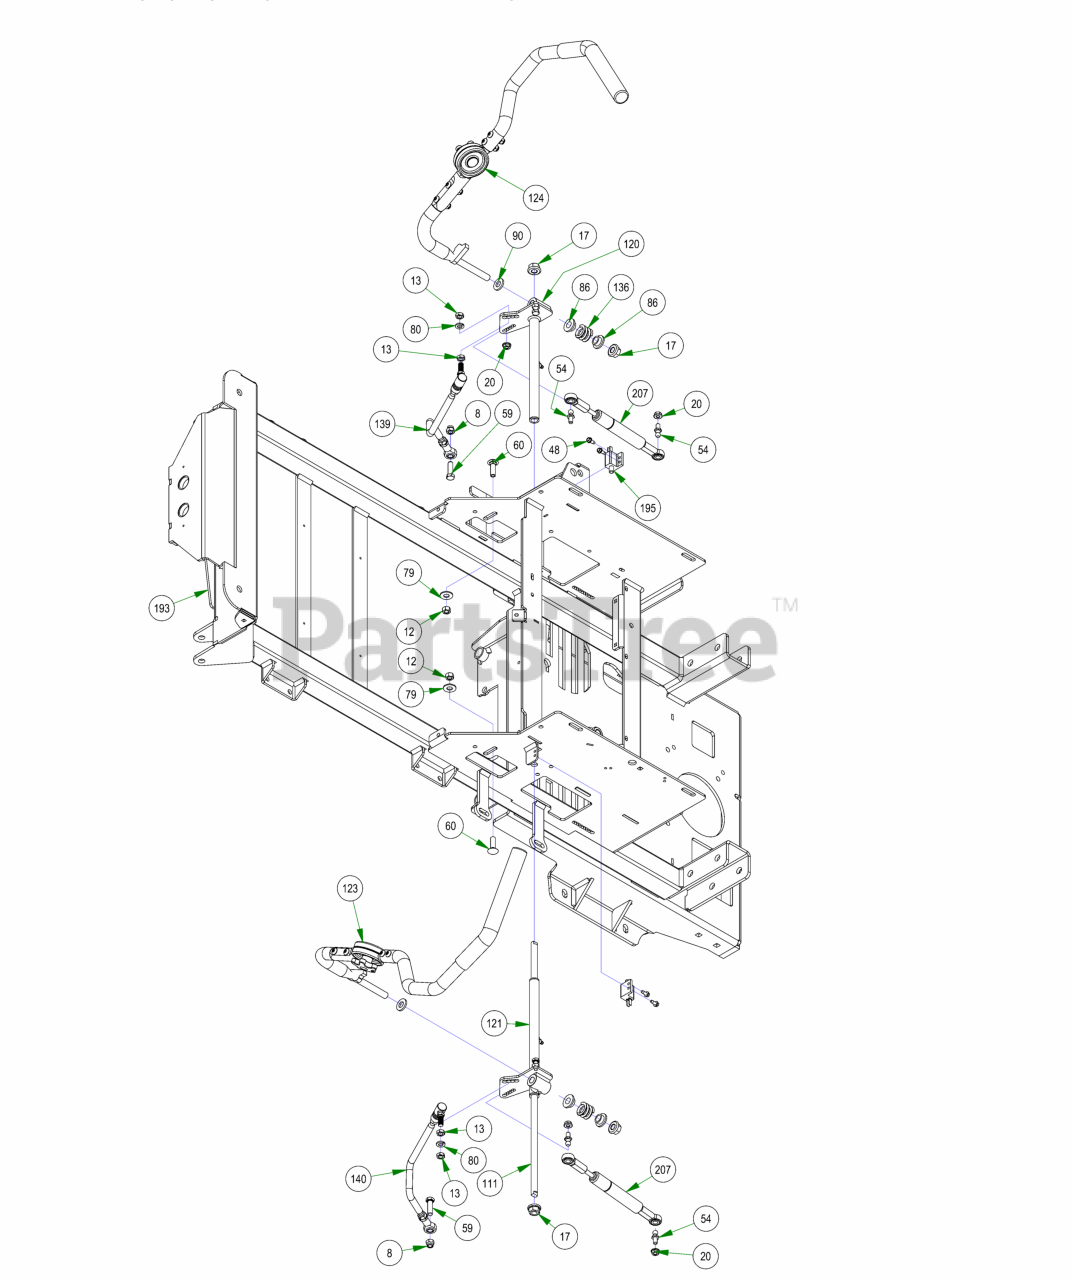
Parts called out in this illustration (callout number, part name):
8	3/8-16 NYLON INSERT LOCKNUT ZINC
12	3/8-16 HEX NUT ZINC
13	3/8-24 HEX NUT ZINC YELLOW
17	1/2-13 NYLON INSERT FLANGE LOCKNUT ZINC
20	5/16-18 HEX SERRATED FLANGE NUT HARD/ZINC
48	12-24 X 1/2 HEX WASHER UNLSOT F TCS ZINC
54	10mm Damper Ball Stud-Steering
59	3/8-16 X 1-1/4 HEX CAP SCREW (GR.5) ZINC
60	3/8-16 X 1-1/4 CARRIAGE BOLT ZINC
79	3/8 FLAT WASHER USS (1" OD) ZINC
80	3/8 SPLIT LOCKWASHER ZINC
86	.525 ID SHOULDER WASHER NYLON
90	.505 ID X 1.000 OD X .125 THICK FLAT WASHER NYLON
111	2021 Maverick Steering Actuator Rod
120	2021 Maverick Drive Arm Actuator RH Assembly
121	2021 Maverick Drive Arm Actuator LH Assembly
123	2018 Adjustable Steering Arm - Left
124	2018 Adjustable Steering Arm - Right
136	Drive Lever Spring
139	Push Rod-Right
140	Push Rod-Left
193	2022 Maverick Frame - Painted
195	Safety Switch
207	Steering Damper
